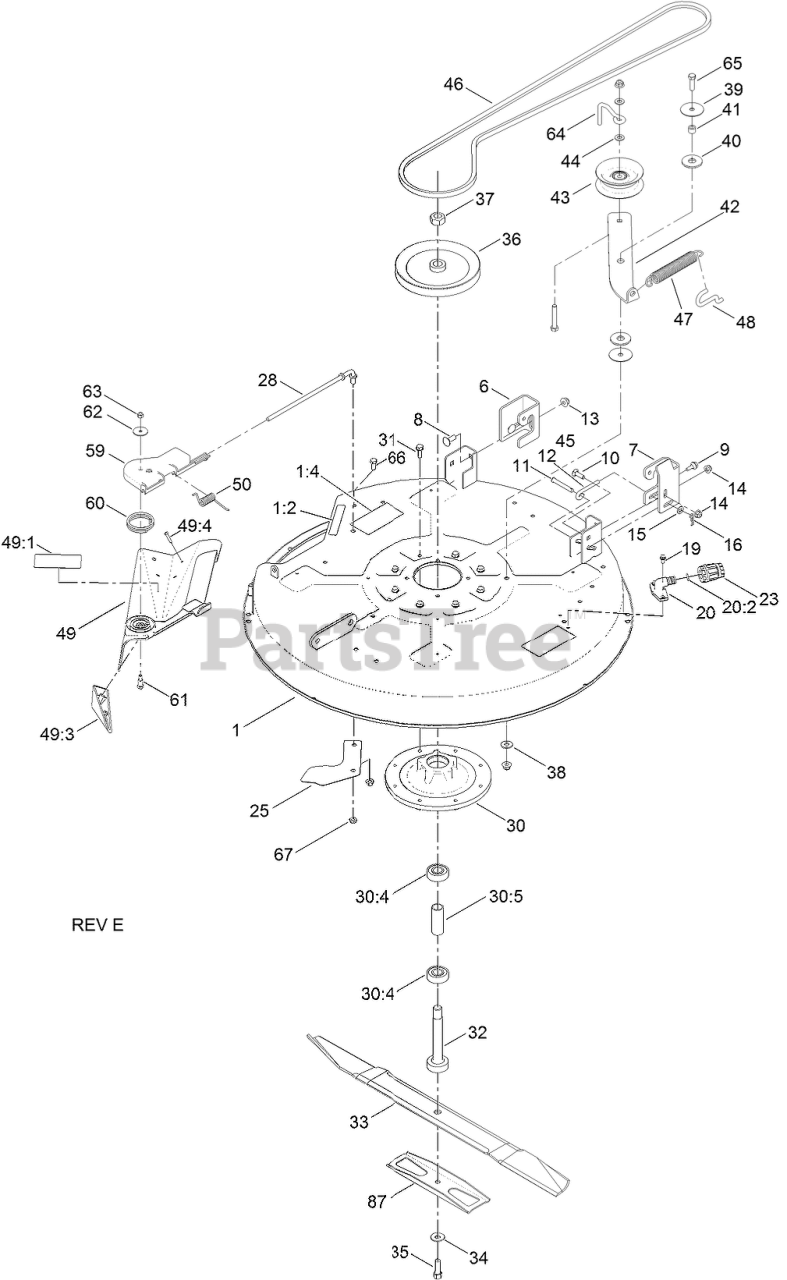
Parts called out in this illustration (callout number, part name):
1	32 INCH DECK AND DECAL ASM
1:2	DECAL-DANGER
1:4	DECAL-DANGER, DECK
6	BRACKET-HANGER, RH
7	BRACKET-HANGER, LH
8	BOLT-CARR
9	SCREW-SHOULDER,HWH
10	SCREW-CARR
11	PIN-CLEVIS
12	ROD-LEVEL, DECK
13	NUT-HF, NI
14	NUT-HF, NI
15	WASHER-PLAIN
16	PIN-COTTER
19	SCREW-HWH
20	FITTING-WASHOUT
20:2	O-RING
23	CONNECTOR-HOSE
25	RAMP-DEFLECTOR
28	ROD-PIVOT
30	SPINDLE HOUSING ASM
30:4	BEARING-BALL
30:5	SPACER-BEARING
31	SCREW-TAPTITE
32	SHAFT-SPINDLE
33	BLADE-RECYCLER, 31.35 INCH
34	WASHER-BELLEVILLE
35	SCREW-HH
36	PULLEY-DECK
37	NUT-HEX
38	WASHER-HARDENED
39	WASHER
40	WASHER-FRICTION, COMPOSITE
41	SPACER
42	ARM-IDLER
43	PULLEY-IDLER, FLAT
44	WASHER-FLAT
45	SCREW-HH
46	V-BELT, 81.8 INCH
47	SPRING-EXTENSION
48	HOOK-RETURN, SPRING
49	32 INCH DEFLECTOR ASM
49:1	DECAL-DANGER
49:3	KICKER
49:4	SCREW-PPH
50	SPRING-TORSION
59	PIVOT-HINGE, DEFLECTOR
60	SPRING-TORSION
61	BOLT-SHOULDER
62	WASHER-FLAT
63	NUT-LOCK, NI
64	GUIDE-IDLER, BELT
65	SCREW-HH
66	SCREW-HH
87	STIFFENER
